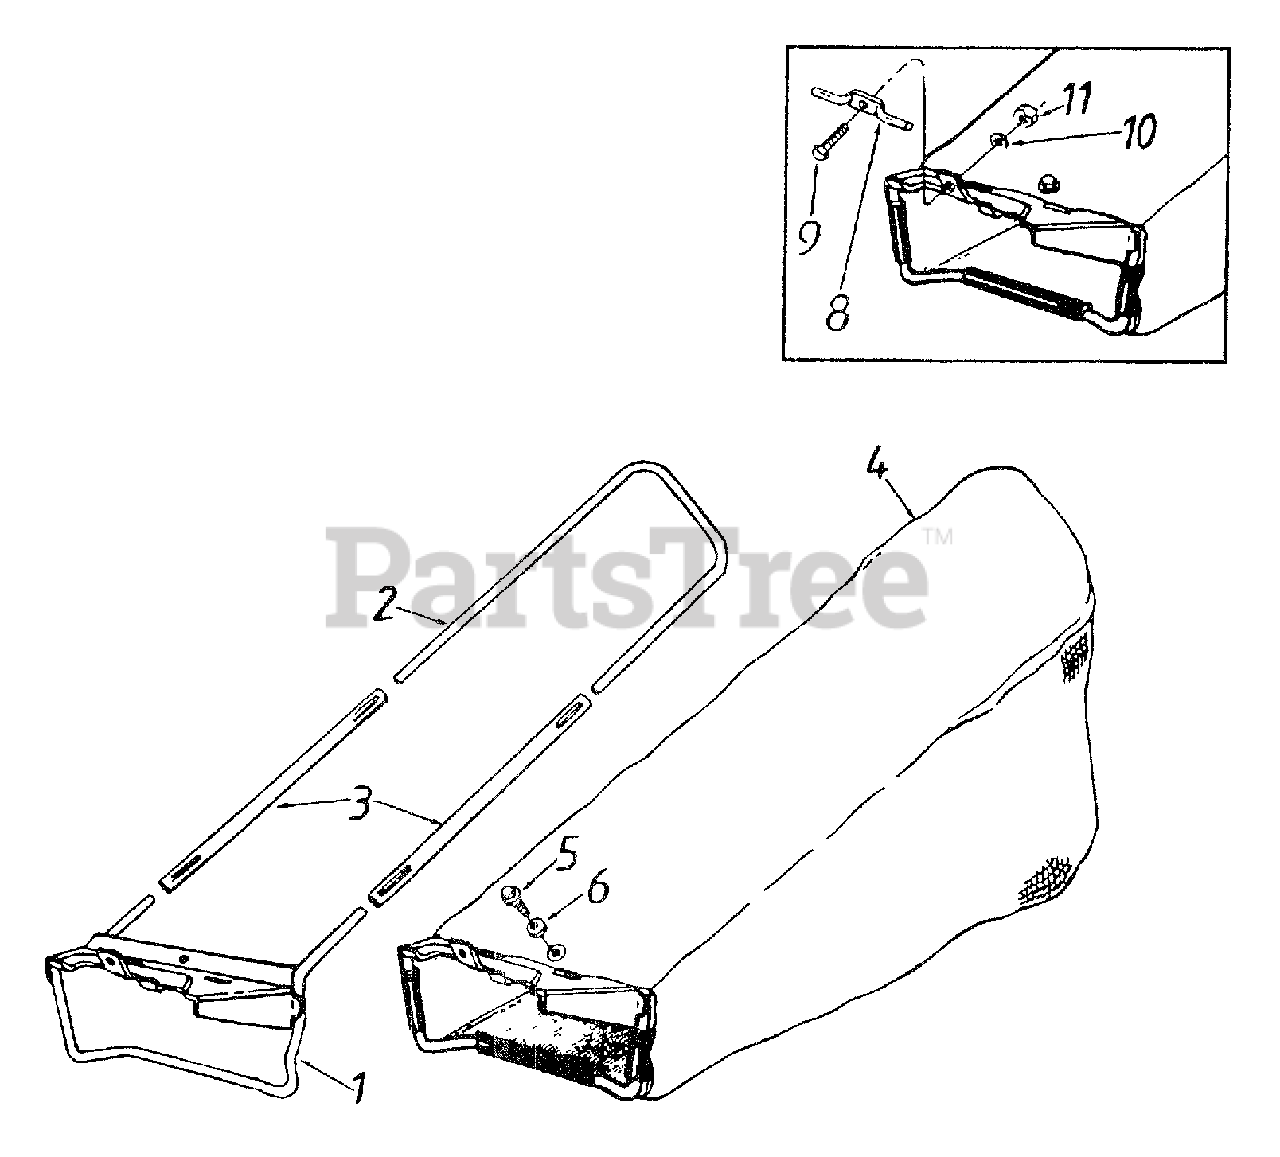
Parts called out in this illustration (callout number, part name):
4	Grass Bag
5	Hex Wash. Hd. TT-Tap Scr. 1/4-20 x 5" Lg.
6	Bell-Wash. 1/4" I.D.
8	Grass Bag Hook
9	Hex Bolt 1/4-20 x .62" Lg.
10	L-Wash. 1/4" I.D.
11	Hex Nut 1/4-20 Thd.
